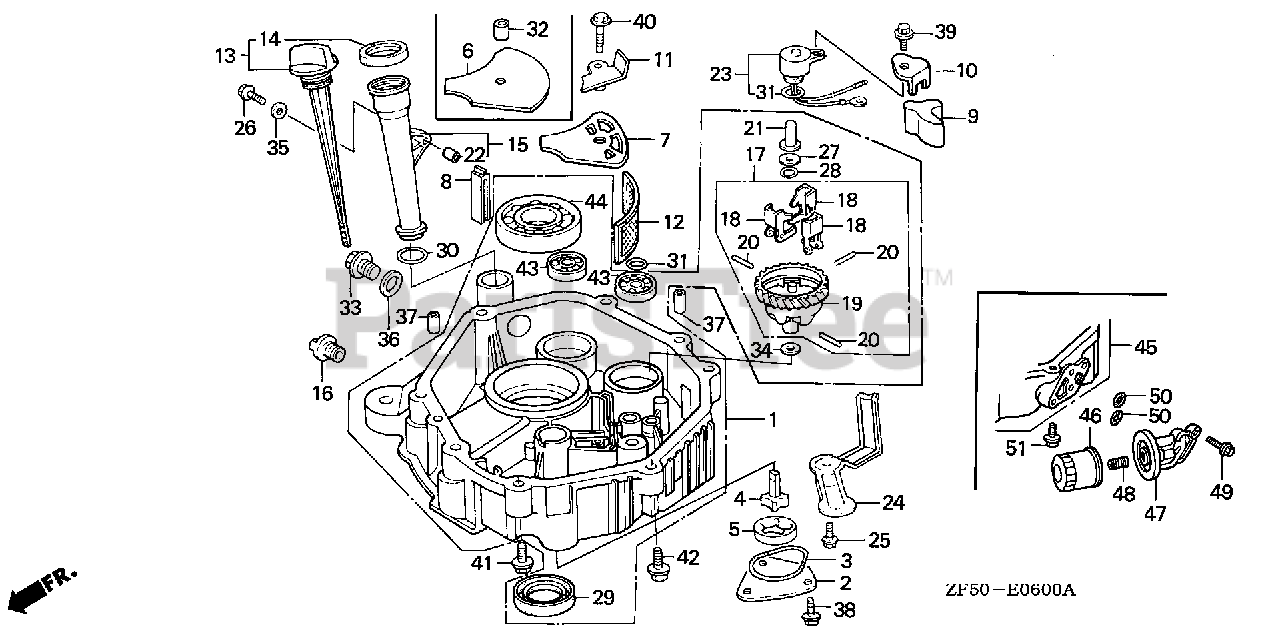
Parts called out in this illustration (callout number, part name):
2	COVER, OIL PUMP
3	O-RING, PUMP COVER
4	ROTOR (INNER)
5	ROTOR, OIL PUMP (OUTER)
6	PLATE, OIL FILTER
8	RUBBER, OIL RETURN
12	SCREEN, OIL FILTER
13	CAP ASSY., OIL FILLER
14	GASKET, OIL FILLER CAP
15	EXTENSION, OIL FILLER
17	GOVERNOR ASSY.
18	WEIGHT, GOVERNOR
19	HOLDER, GOVERNOR WEIGHT
20	PIN, GOVERNOR WEIGHT
21	SLIDER, GOVERNOR
22	COLLAR, EXTENSION
26	BOLT, FLANGE (6X35) (CT200)
28	CLIP, GOVERNOR HOLDER
29	OIL SEAL (35X52X8)
30	O-RING (22.1X2.2)
31	O-RING (11.8X2.4)
32	COLLAR, OIL FILTER SETTING
33	BOLT, DRAIN PLUG (20MM)
34	WASHER, PLAIN (6MM)
36	WASHER, DRAIN PLUG (20MM)
37	PIN, DOWEL (8X12)
38	BOLT, FLANGE (6X12)
40	BOLT, FLANGE (6X25)
41	BOLT, FLANGE (8X40)
43	BEARING, RADIAL BALL (6202)
44	BEARING, RADIAL BALL (6207)
45	PAN ASSY., OIL
46	FILTER, OIL (FILTECH TOYO ROKI) (SOLD INDIVIDUALLY)
46	FILTER, OIL (TOYO ROKI) (SOLD INDIVIDUALLY)
47	BASE, OIL FILTER
48	HOLDER, OIL FILTER
49	BOLT, FLANGE (6X25) (CT200)
50	O-RING (11X1.9) (NOK)
51	BOLT, FLANGE (8X60)
